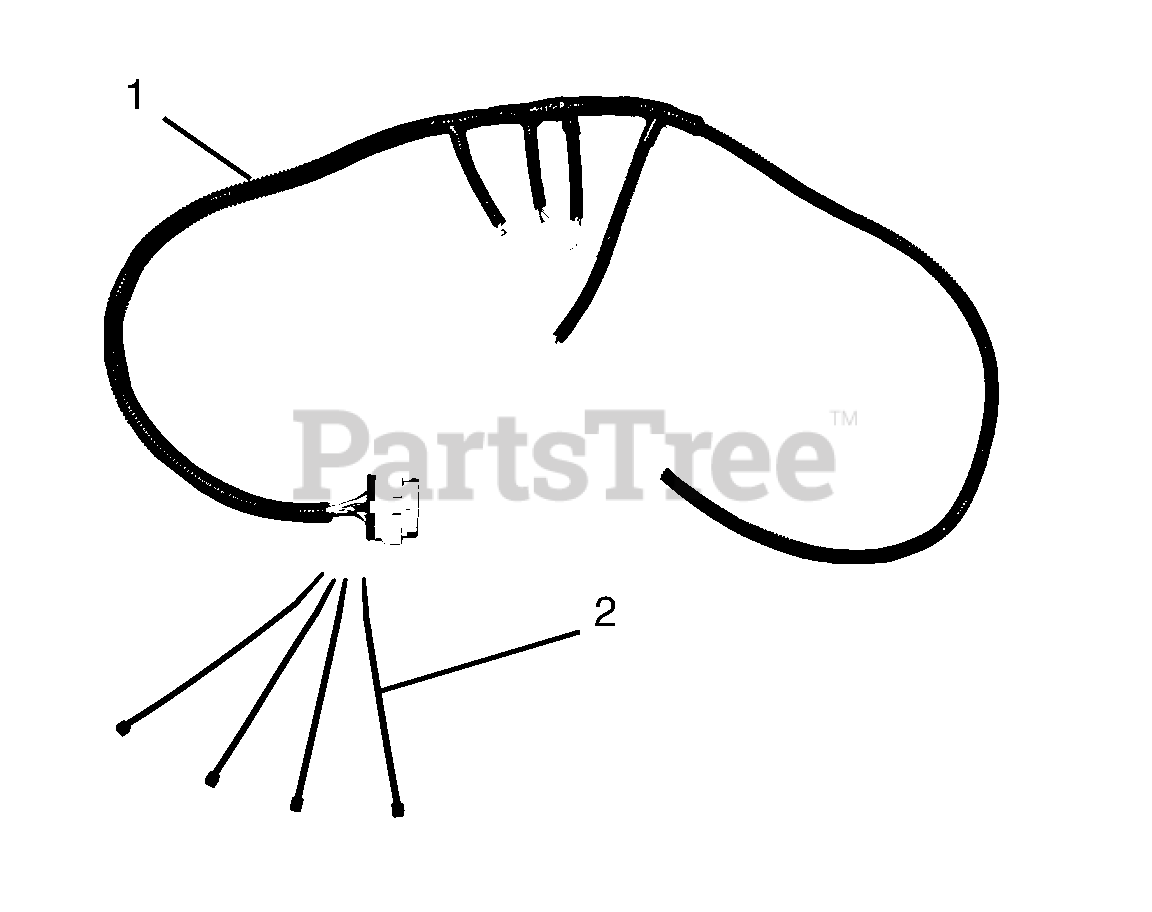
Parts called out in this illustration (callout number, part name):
1	Eye-Q™ Accessory Wire Harness
2	Cable Tie, 5-1/2-in Long
2	Eye-Q™ Accessory Wire Harness Kit
